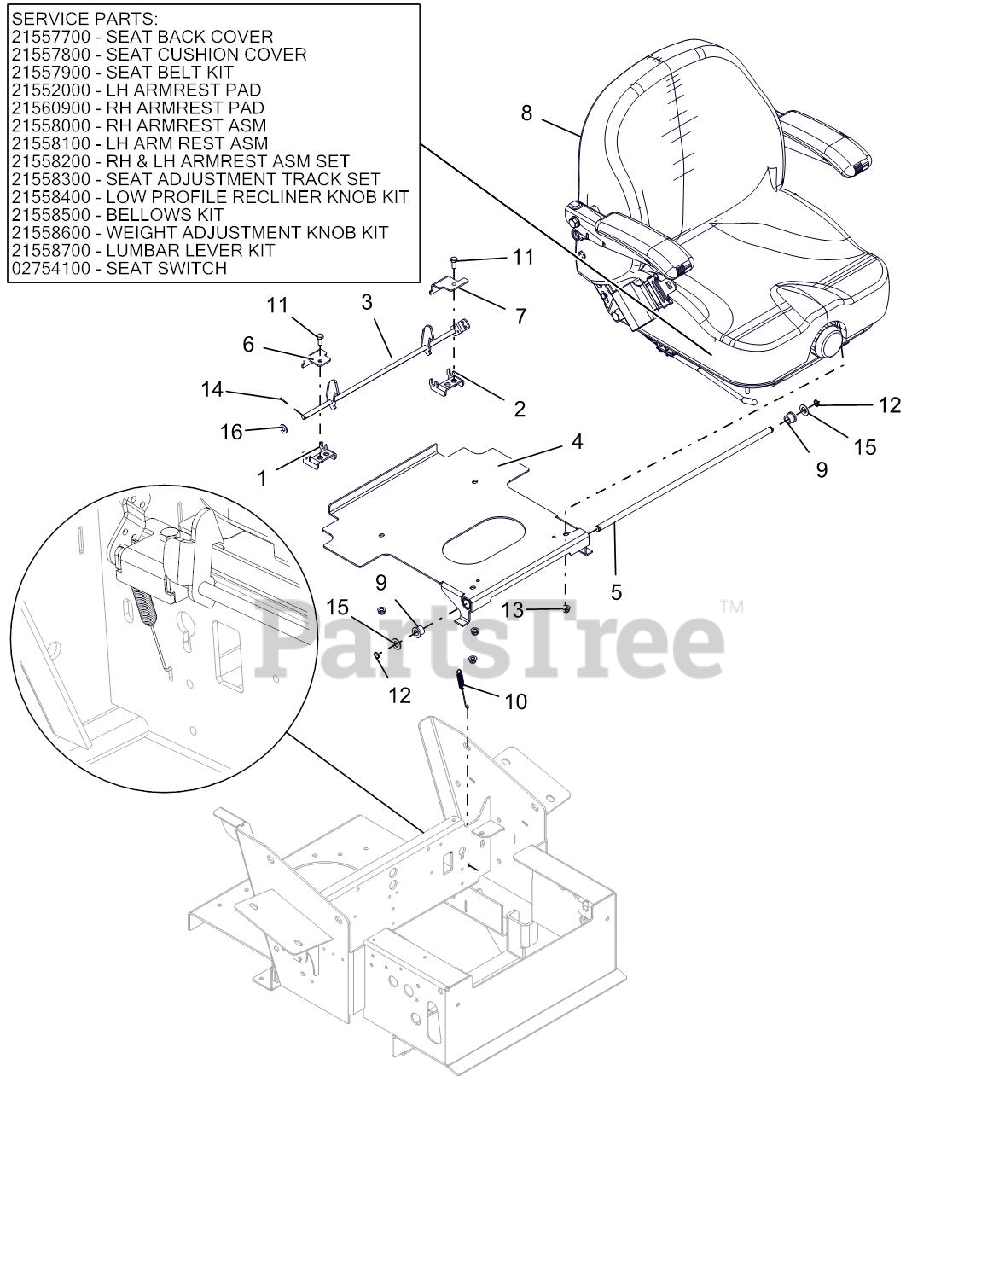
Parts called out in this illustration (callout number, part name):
1	WLDMT, PT/PT100 RH SEAT LATCH MOUNT-BLACK
2	WLDMT, PT/PT100 LH SEAT LATCH MOUNT-BLACK
3	WLDMT, PT/PT100 SEAT LATCH
4	WLDMT, PRO-TURN 100 SEAT PLATE (BLACK)
5	SHAFT, PT/PT100 SEAT PIVOT
6	MOUNT, PT/PT100 RH TOP SEAT LATCH-BLACK
7	MOUNT, PT/PT100 LH TOP SEAT LATCH-BLACK
8	SEAT, FULL SUSPENSION
8	SEAT BACK COVER
8	SEAT CUSHION COVER
8	SEAT BELT KIT
8	LH ARMREST PAD
8	RH ARMREST PAD
8	RH ARMREST ASM
8	LH ARM REST ASM
8	RH & LH ARMREST ASM SET
8	SEAT ADJUSTMENT TRACK SET
8	LOW PROFILE RECLINER KNOB KIT
8	BELLOWS KIT
8	WEIGHT ADJUSTMENT KNOB KIT
8	LUMBAR LEVER KIT
8	SEAT SWITCH
9	BSHG, SHLDR EP .358-16X.30 HEX YZ
10	SPRG, EXTENSION
11	BOLT, HEX 0.313-18X0.75 GR5
12	RG-RTNG-EXT .500x.050
13	NUT-LK-NYL-FLG .31-18 YWZC
14	PIN-CTR .09X.75 EXTPRSQCT YWZ
15	WSHR-FL-STL .531X1.000X.063 YWZC
16	WSHR-FL-STL.406X.812X.065 YWZ
